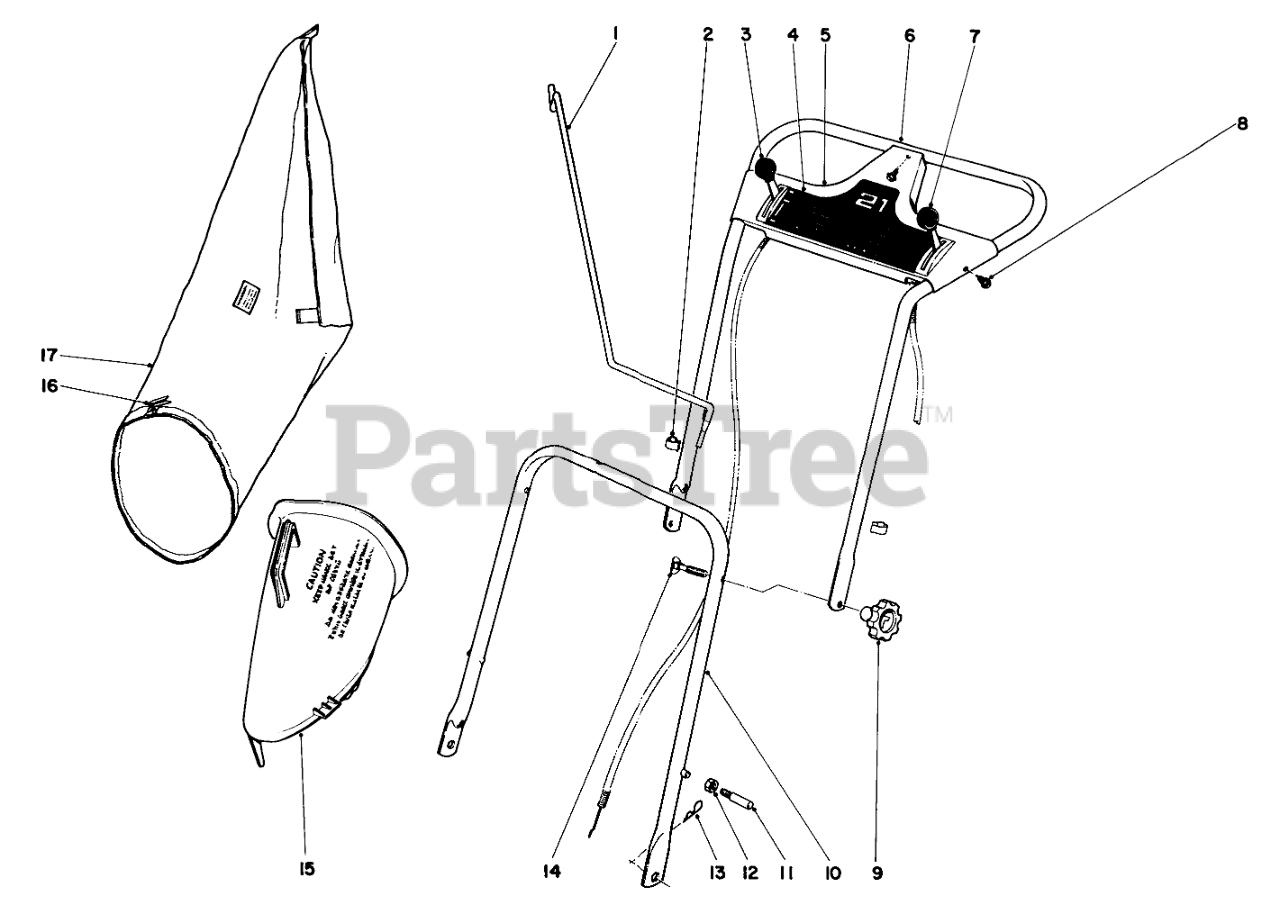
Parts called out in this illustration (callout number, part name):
1	BAG HANGER ROD
2	CONTROL WIRE CLIP
3	Throttle Control
4	Escutcheon Plate Decal
5	Escutcheon Plate
6	Upper Handle
7	Traction Control
8	SCREW-HWHTF
9	Handle Release Knob
10	Lower Handle
11	Handle Pin
12	Nut
13	PIN-COTTER, HAIR
14	HANDLE SCREW
15	BAG ATTACHMENT
16	BAG CORD FASTENER
17	Grass Bag (Incl. Ref. No. 16)
